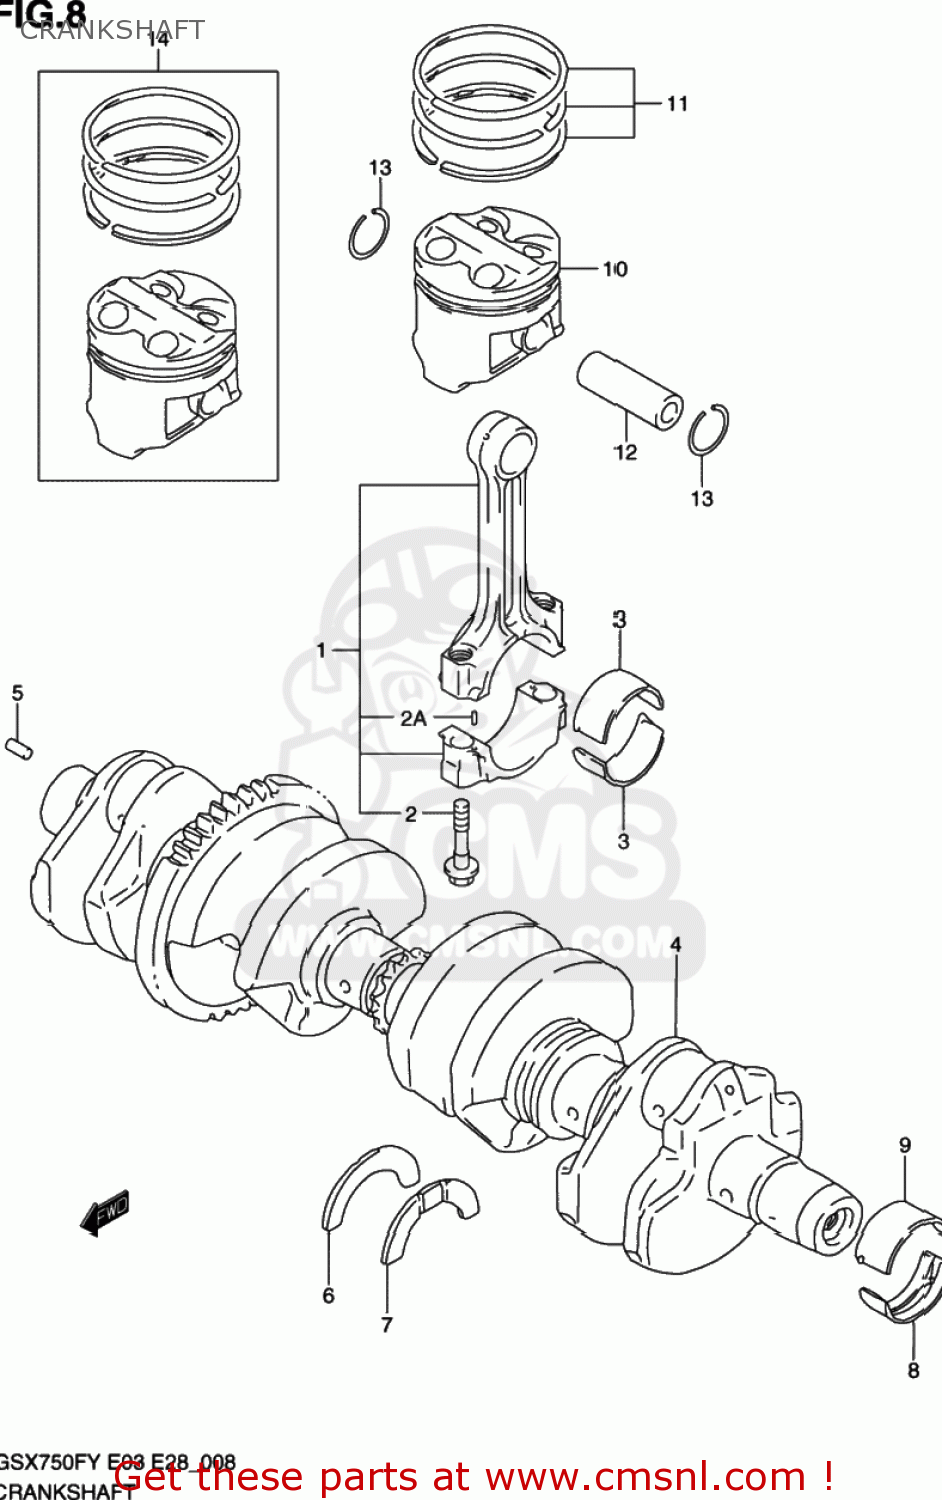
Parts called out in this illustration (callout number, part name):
1	CONNECTING ROD ASSY
2	BOLT,CONNECTING ROD
2A	PIN,CONNECTING ROD
3	BEARING,CRANK PIN
4	CRANKSHAFT SET
5	PIN
6	PLATE,CRANK THRUST
7	PLATE,CRANK THRUST
8	BEARING,CRANKSHAFT LWR
9	BEARING,CRANKSHAFT UPR
10	PISTON
11	RING SET,PISTON
12	PIN,PISTON
13	CIRCLIP
14	PISTON SET(OS:0.5)
